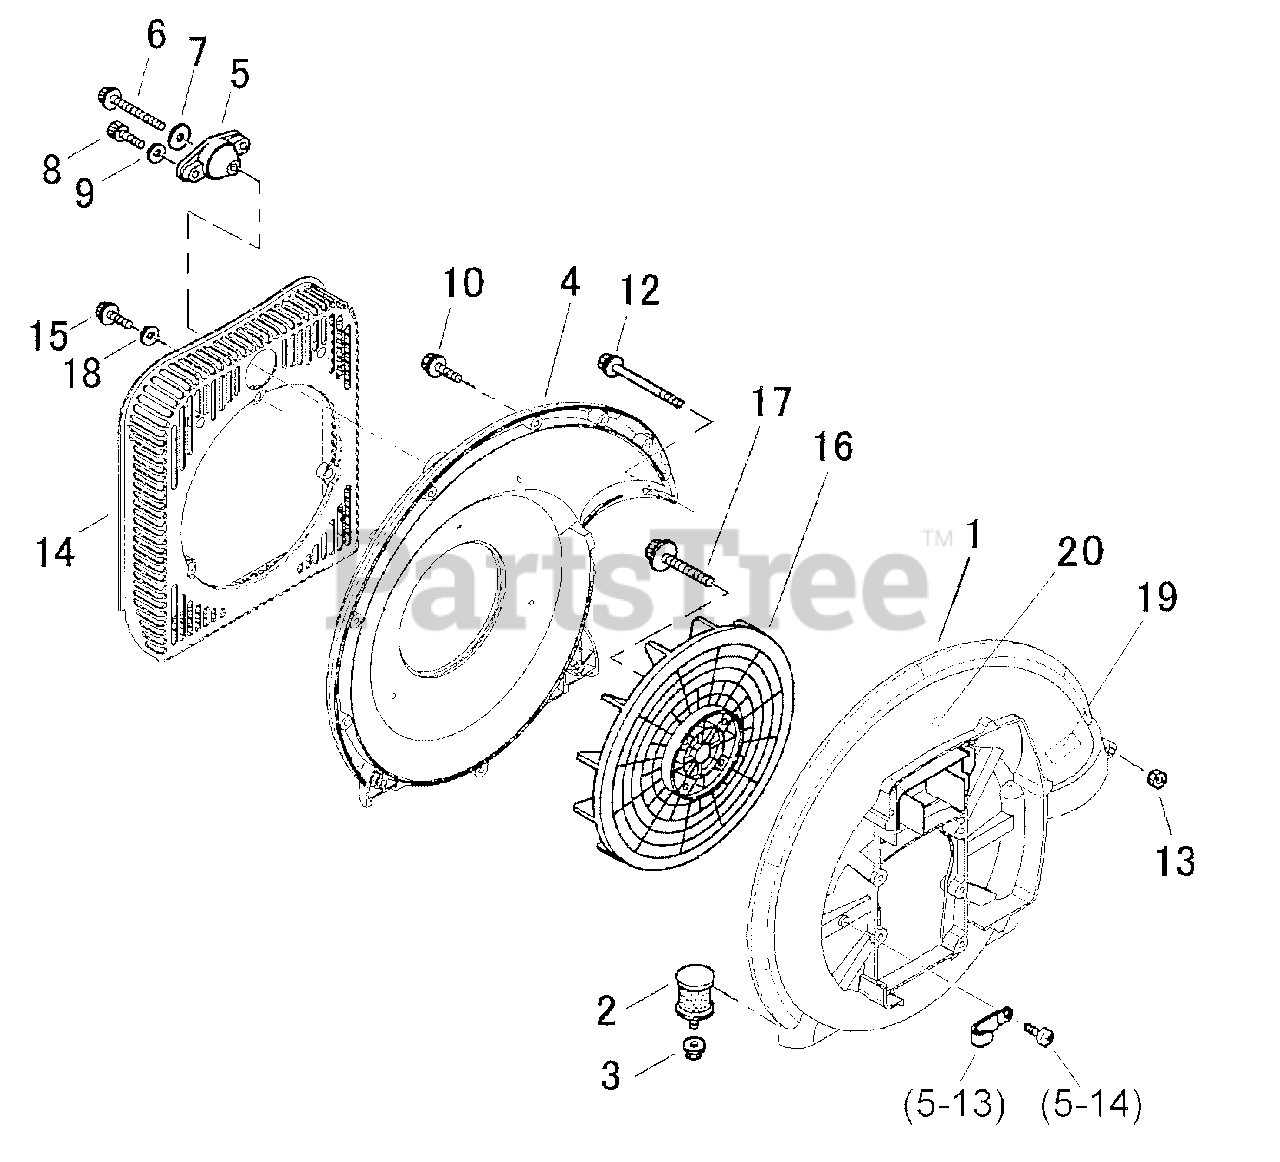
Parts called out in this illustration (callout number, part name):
1	CASE, VOLUTE
2	CUSHION, AV 6
3	NUT, FLANGE M6
4	COVER, FAN
5	CUSHION, AV 5
6	BOLT TAPPING M5
7	WASHER Ø25ר5.5×2
8	BOLT M5×16
9	WASHER Ø15ר5.2×1.6
10	BOLT M5×20
12	BOLT M5×70
13	NUT M5
14	COVER, INTAKE
15	BOLT M5×20
16	FAN
17	BOLT M6×40
18	WASHER 5 MM
19	LABEL, CAUTION - AIR INTAKE
20	LABEL, NOISE
